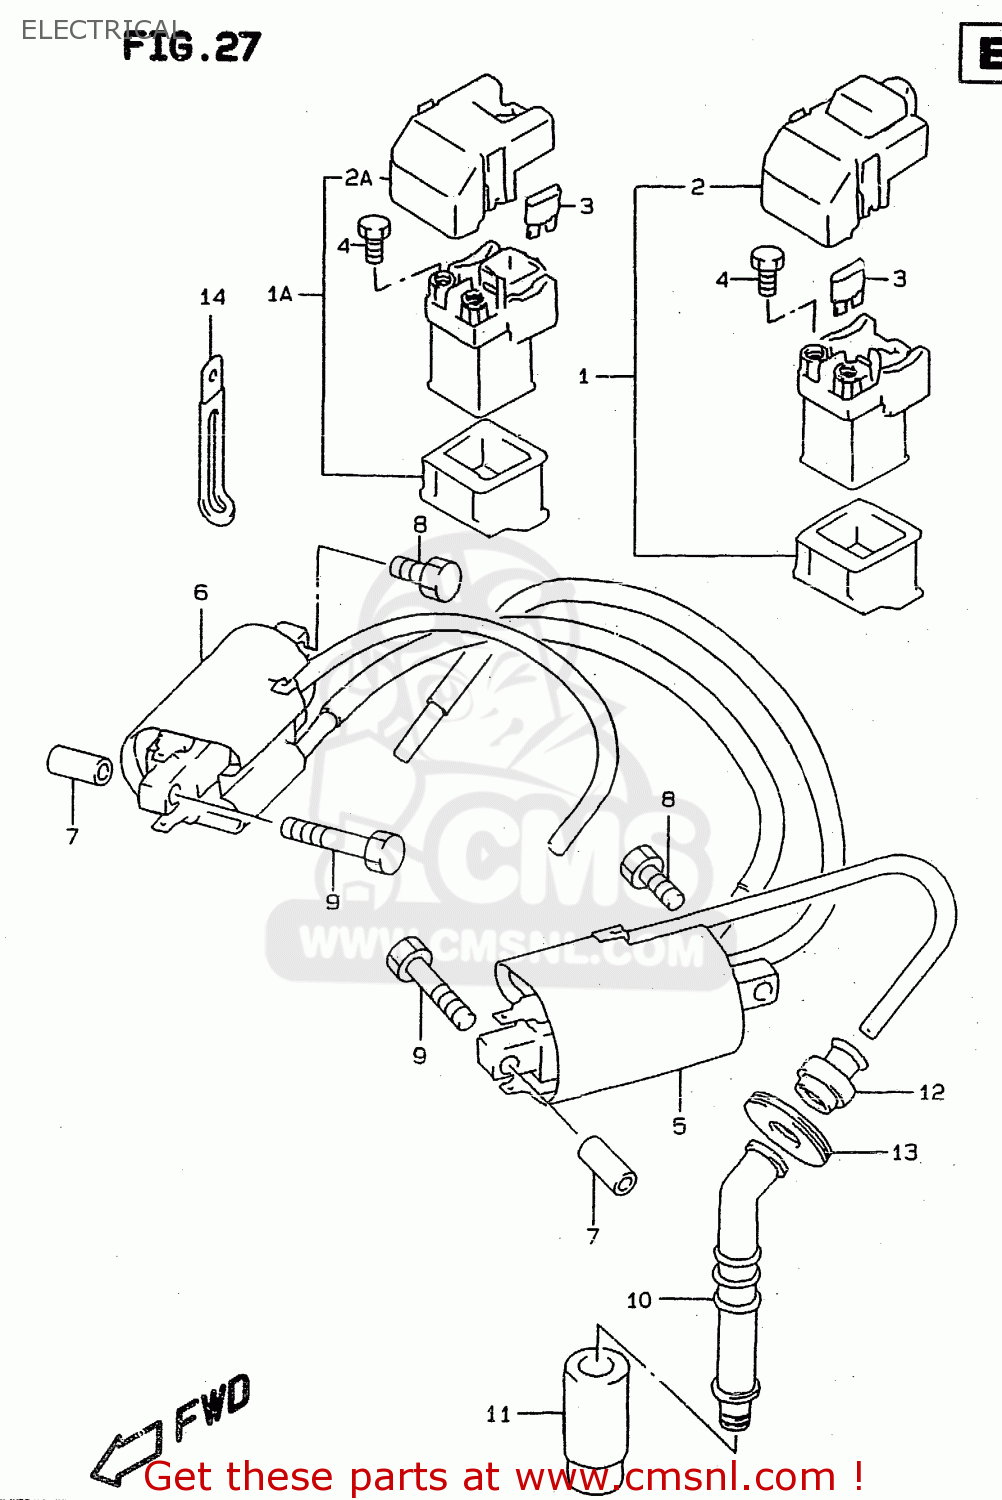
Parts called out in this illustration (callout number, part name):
1	RELAY ASSY,STARTING MOTOR
1A	RELAY ASSY,STARTING MOTOR
2	COVER,RELAY ASSEMBLY
2A	COVER,RELAY ASSEMBLY
3	FUSE(30A)
4	SCREW(6X8)
5	COIL ASSY,IGNITION
6	COIL ASSY,IGNITION
7	SPACER(6.2X15.5X16.5)
8	BOLT
9	BOLT
10	CAP ASSY,SPARK PLUG
11	SEAL,SPARK PLUG
12	SEAL,HIGH TENSION CORD
13	COVER,SPARK PLUG CAP
14	CLAMP
